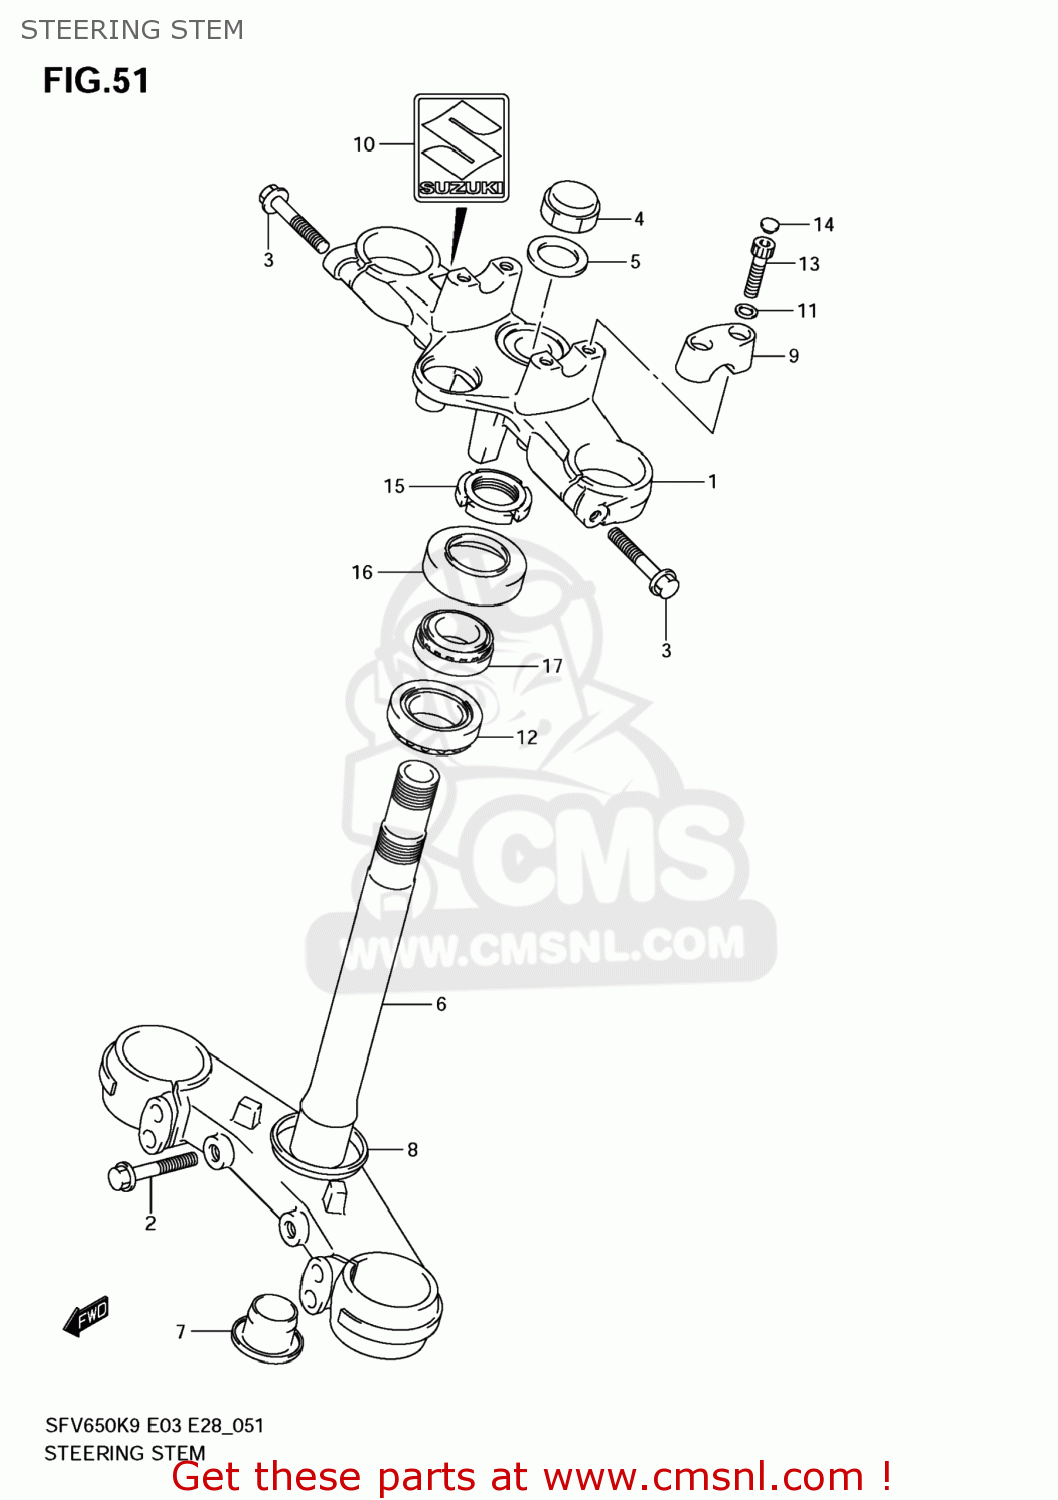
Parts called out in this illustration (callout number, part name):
1	HEAD,STEERING STEM
2	BOLT
3	BOLT
4	NUT,CAP
5	WASHER
6	STEM,STEERING
7	CAP
8	SEAL,STEERING LWR
9	HOLDER,HANDLE
10	EMBLEM,S
11	WASHER
12	BEARING(30X55X17)
13	BOLT
14	CAP(OD:11)
15	NUT,STEERING STEM
16	DUST SEAL,STEERING UPR
17	BEARING(25X47X15)
